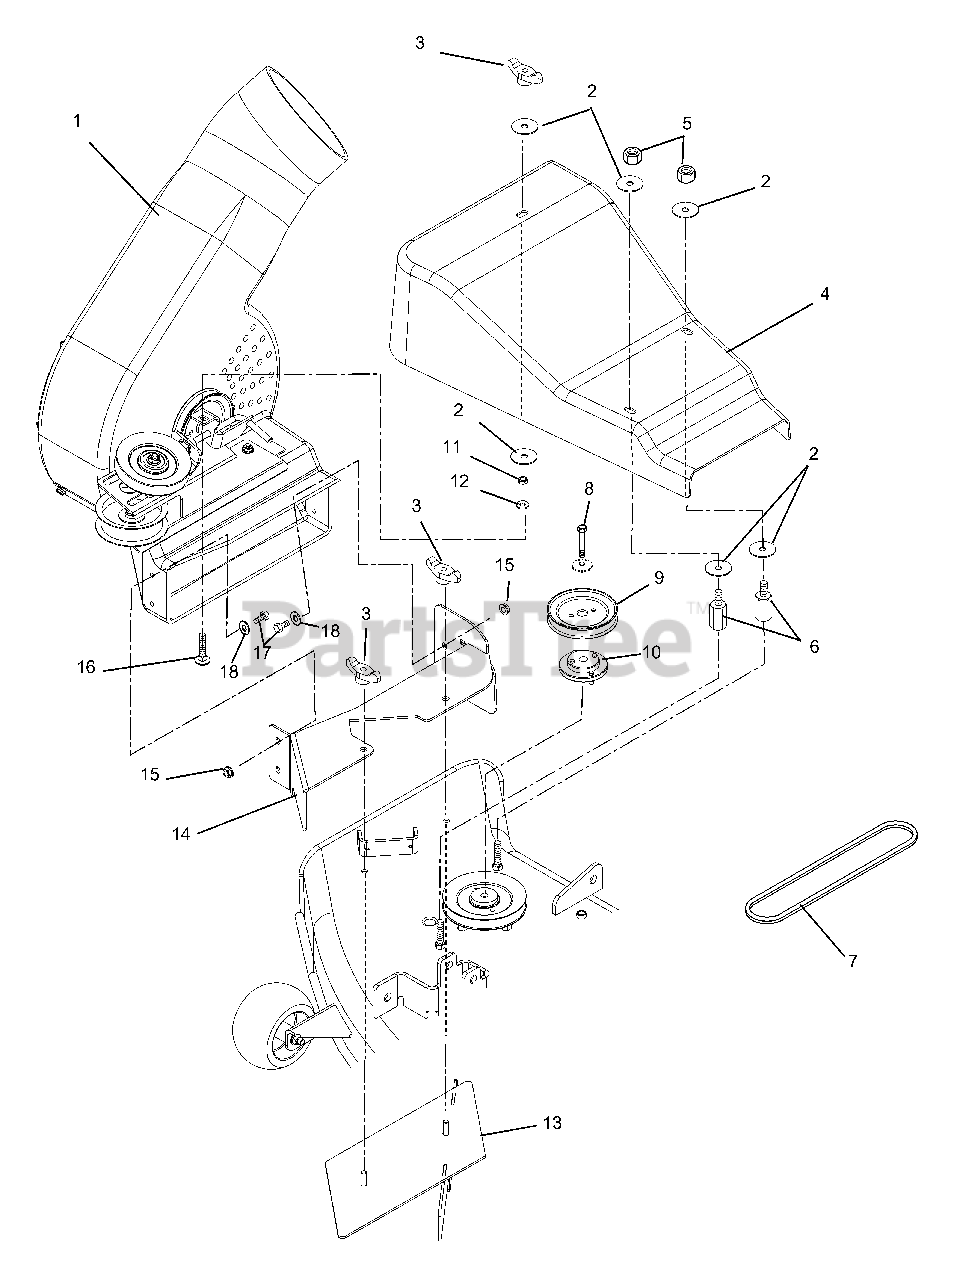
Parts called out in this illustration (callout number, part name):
1	BLOWER HSG W/DECAL
2	WSHR-FL-STL .380X1.50X.062 YWZ
3	KNOB - WING .312-18 UNC
4	COVER, 50" ZOOM BAGGER BELT
5	@NUT-LK-CTR .31-18 YWZC
6	STANDOFF, 2.75 X 5/16-18
7	V-BELT, 4L-RAW EDGE
8	BLT-HEX .38-16X1.75 GR8 M-EPYZ
9	SHEAVE, 4.00 DIA.
10	ASSEMBLY, SHEAVE ADAPTER
11	NUT- JAM .312-18 YWZC
12	@WSHR-FL-STL.312X.734X.065 YWZ
13	WMT, BAGGER DOUBLER PLATE
14	WMT, 50" ZOOM BAGGER MTG BRKT
15	@NUT-LK-NYL-FLG .25-20 YWZC
16	@BLT-RDHDSQNK .31-18X1.50 G5YZ
17	@BLT-HEX .25-20X1.00 GR5 YWZC
18	@WSHR-FL-STL.281X.62X.065 YWZC
